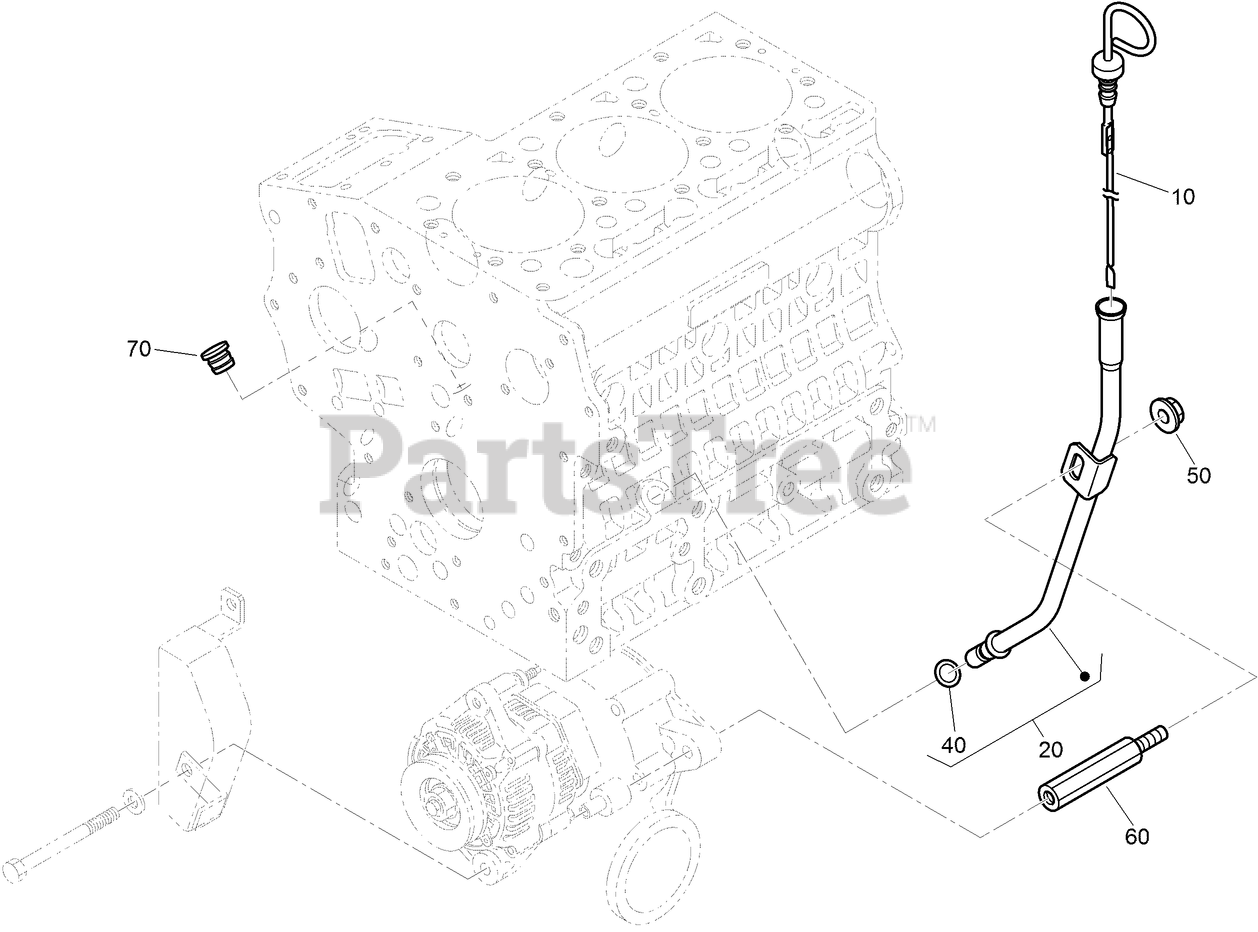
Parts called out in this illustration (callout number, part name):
10	GAUGE-OIL
20	OIL GAUGE GUIDE ASM
40	O-RING
50	NUT-FLANGE
60	SUPPORT-GUIDE, GAUGE
70	PLUG-GAUGE, OIL
